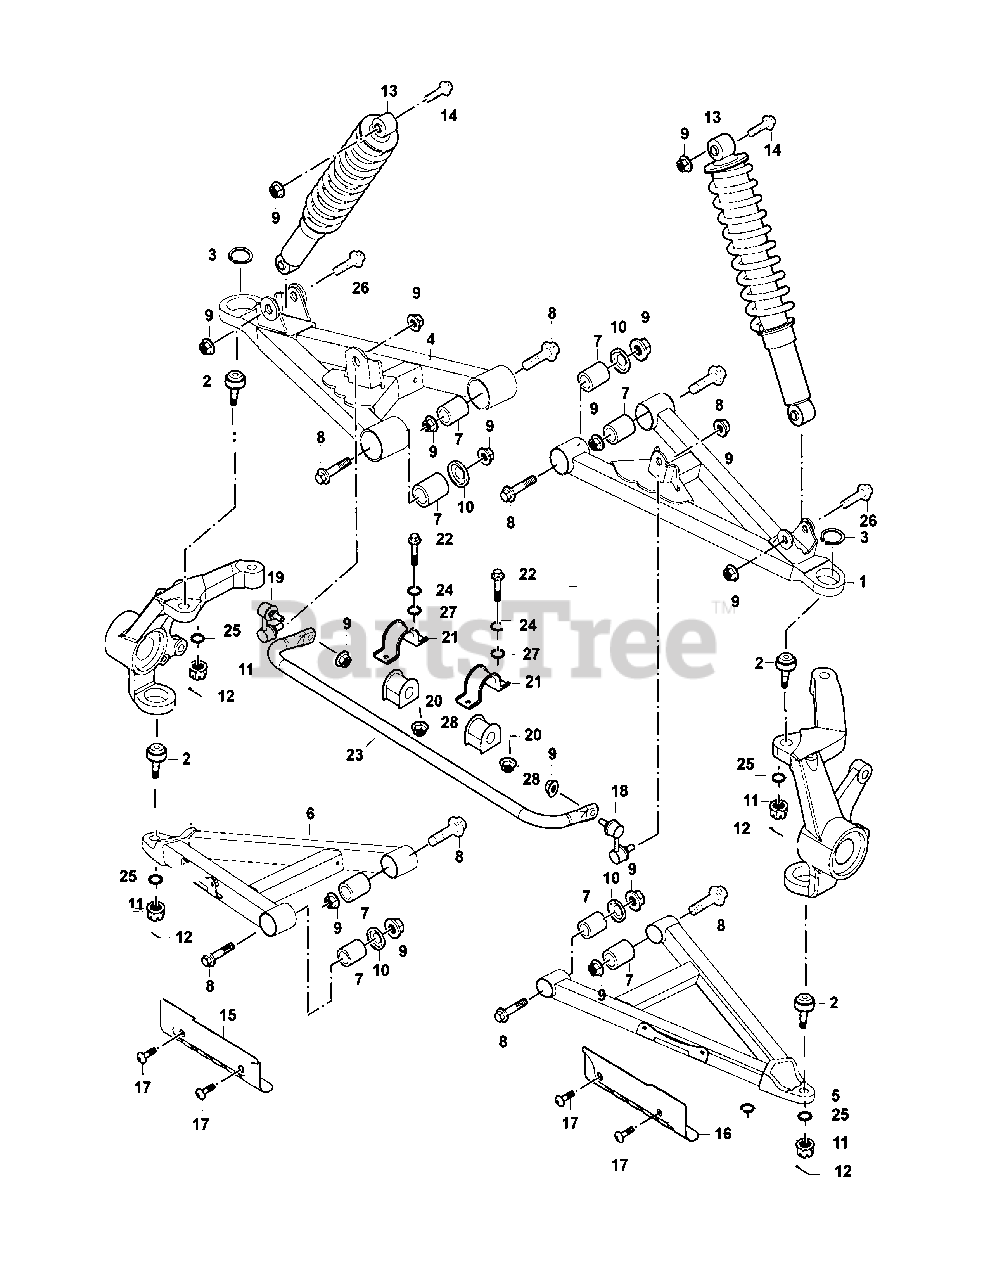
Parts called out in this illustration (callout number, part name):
1	Left front upper swing arm
2	Joint A, suspension
3	Circlip D0=30
4	Right front upper swing arm
5	Left front lower swing arm
6	Right front lower swing arm
7	Bushing 10×23×50
8	Bolt M10×1.25×78
9	Hexagon flange nut M10×1.25
10	Nylon Bushing
11	Hexagon nut M12×1.25
13	Front shock absorber
14	Bolt M10×1.25×60
15	Protective Board, Rear Right Lower Swing Arm
16	Protective Board, Rear Left Lower Swing Arm
17	Cross large plate head screw M6×16
18	Left Tie-Rod, Anti-Roll Bar
19	Right Tie-Rod, Anti-Roll Bar
20	U-type Rubber bush III
21	Press Block, Rear Anti-Roll Bar
22	Hexagon Flange Bolt M8×22
23	Front anti-roll bar
24	Spring Washer -8
25	Spring Washer -12
26	Bolt M10×1.25×60
27	Cushion 8.4×16×1.6
28	Hexagon Flange Lock Nut M8 (Metallic Insert)
